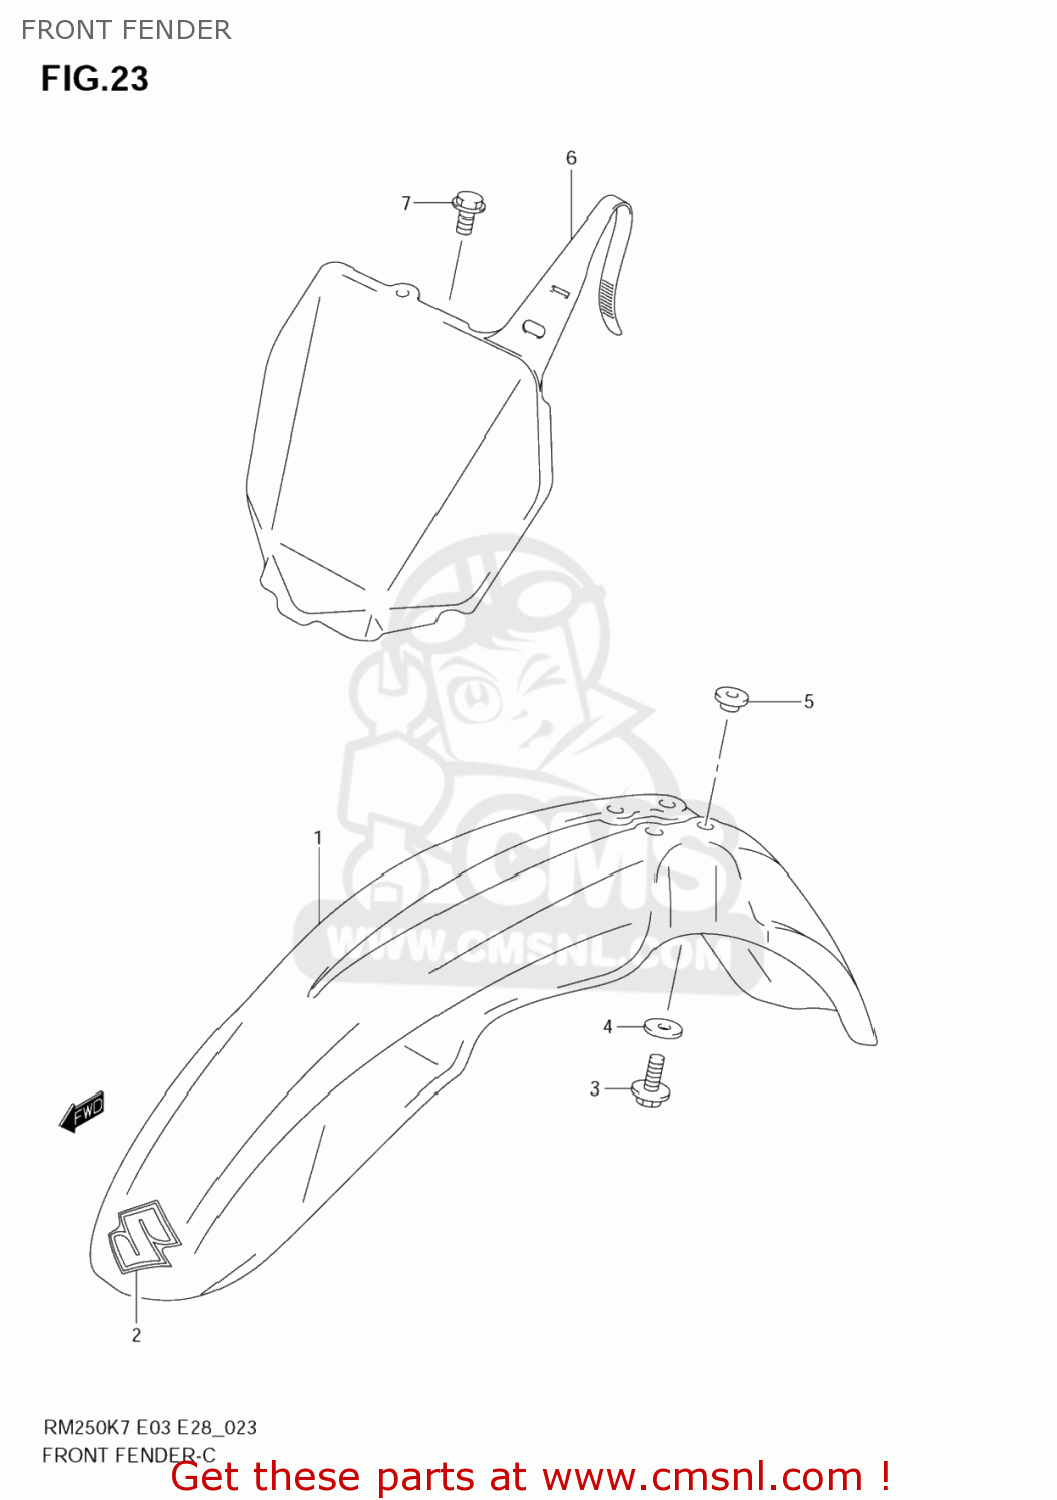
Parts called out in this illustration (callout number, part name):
1	FENDER,FR
2	EMBLEM,S
3	BOLT
4	WASHER(6.5X28X1.6)
5	WASHER
6	PLATE,NUMBER FR
7	BOLT(6X12)
